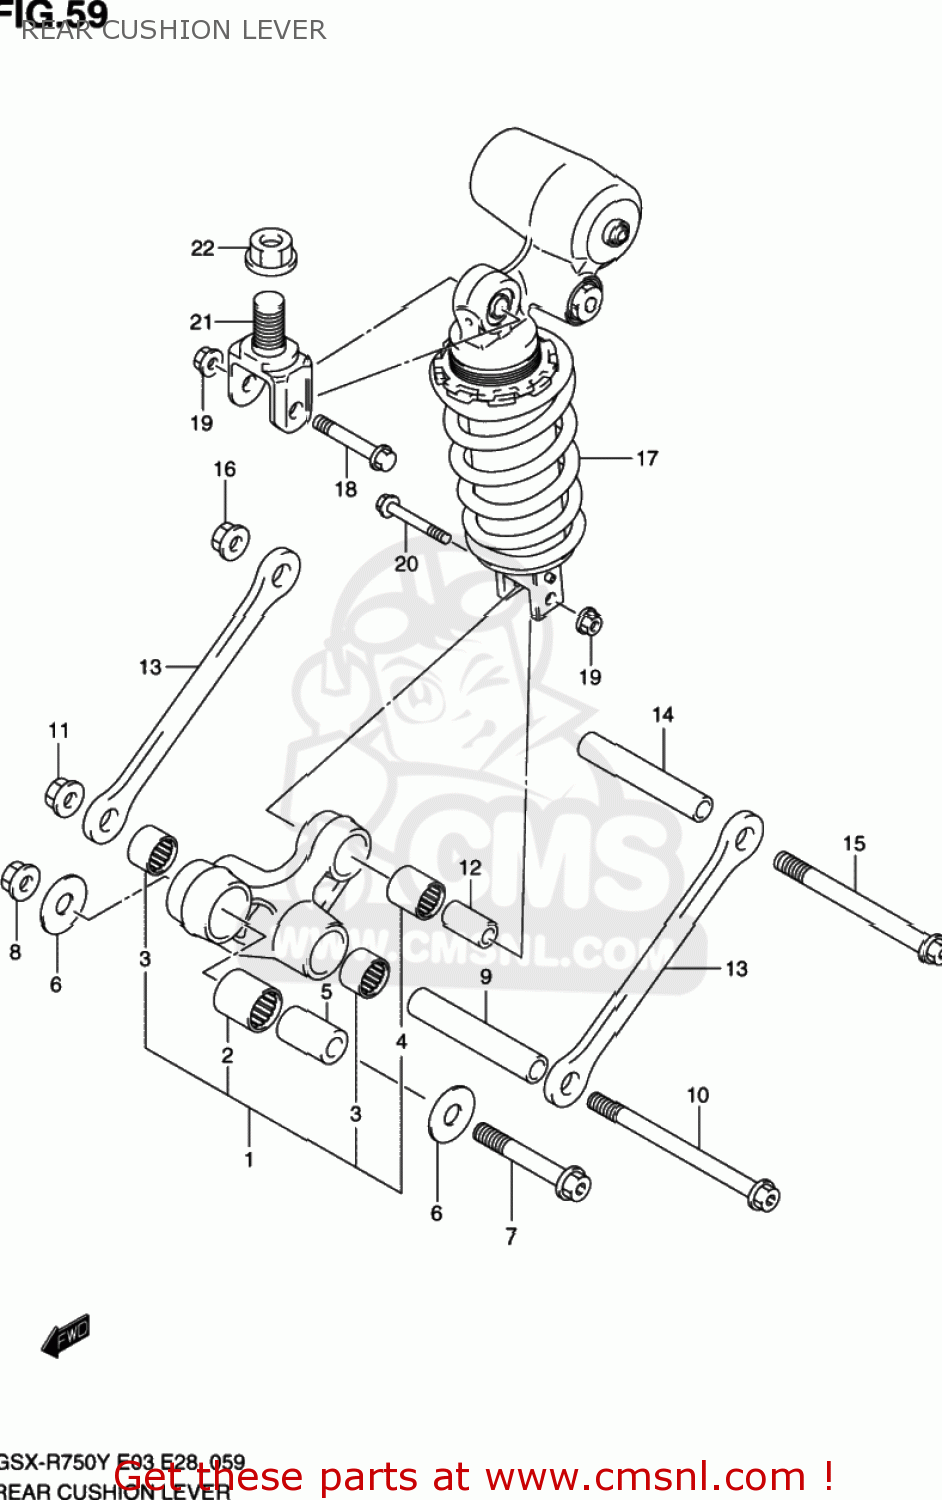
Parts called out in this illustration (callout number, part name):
1	LEVER SET,REAR CUSHION
2	BEARING(20X27X30)
3	BEARING(17X24X20)
4	BEARING(17X24X26)
5	SPACER,RR CUSHION LEVER FR
6	WASHER(12X34X1)
7	BOLT,RR CUSHION LEVER FR
8	NUT 12MM
9	SPACER,RR CUSHION LEVER CTR
10	BOLT,RR CUSHION LEVER CTR
11	NUT 12MM
12	SPACER,RR CUSHION LEVER
13	ROD,RR CUSHION
14	SPACER,RR CUSHION LEVER CTR
15	BOLT,RR CUSHION LEVER CTR
16	NUT 12MM
17	ABSORBER ASSEMBLY,REAR SHOCK
18	BOLT(10X55)
19	NUT
20	BOLT(10X55)
21	BRACKET,RR SHOCK ABSORBER UPR
22	NUT
